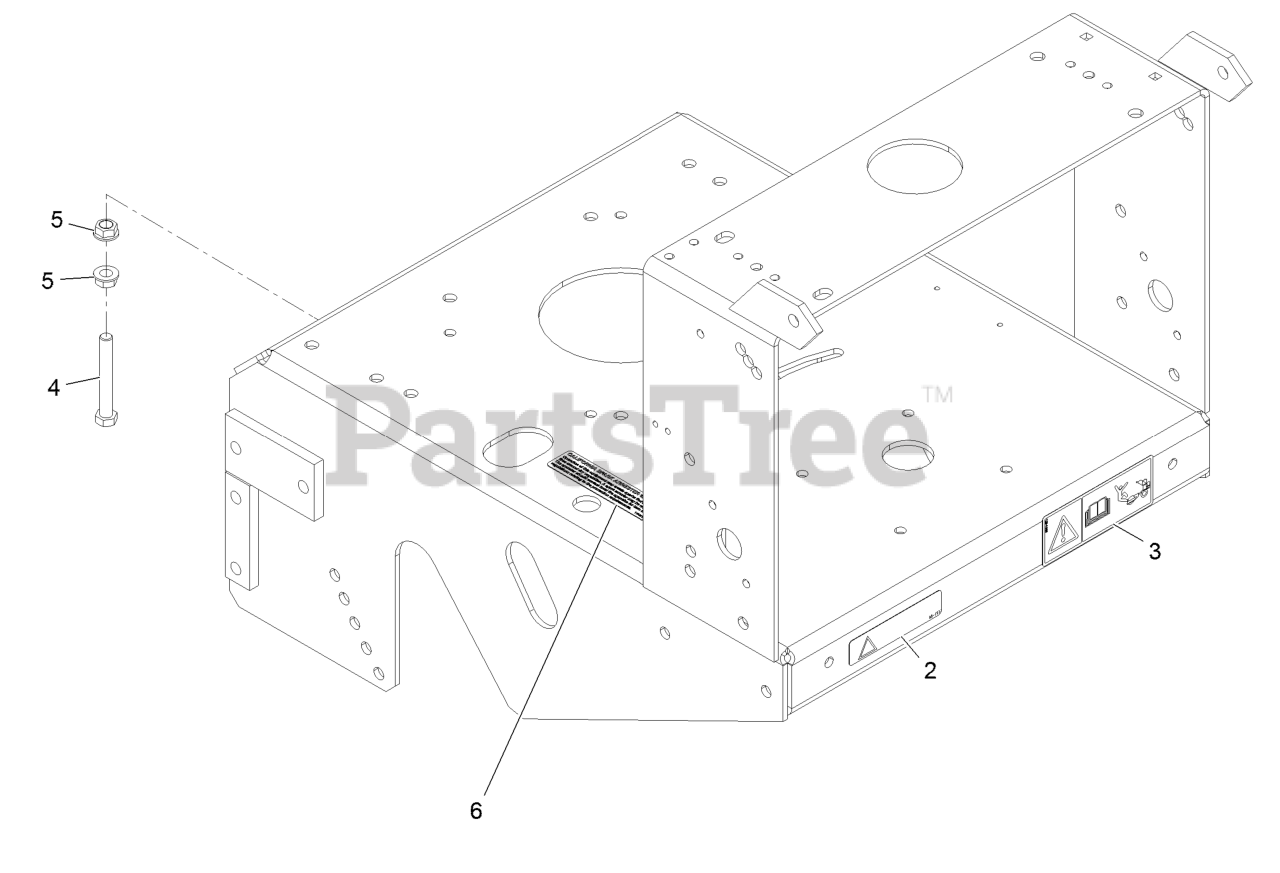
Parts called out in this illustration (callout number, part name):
2	Decal-Warning
3	Decal-Warning, Sulky
4	Screw-HH
5	Nut-HHF, Whiz
6	Decal-Arrester, Spark
